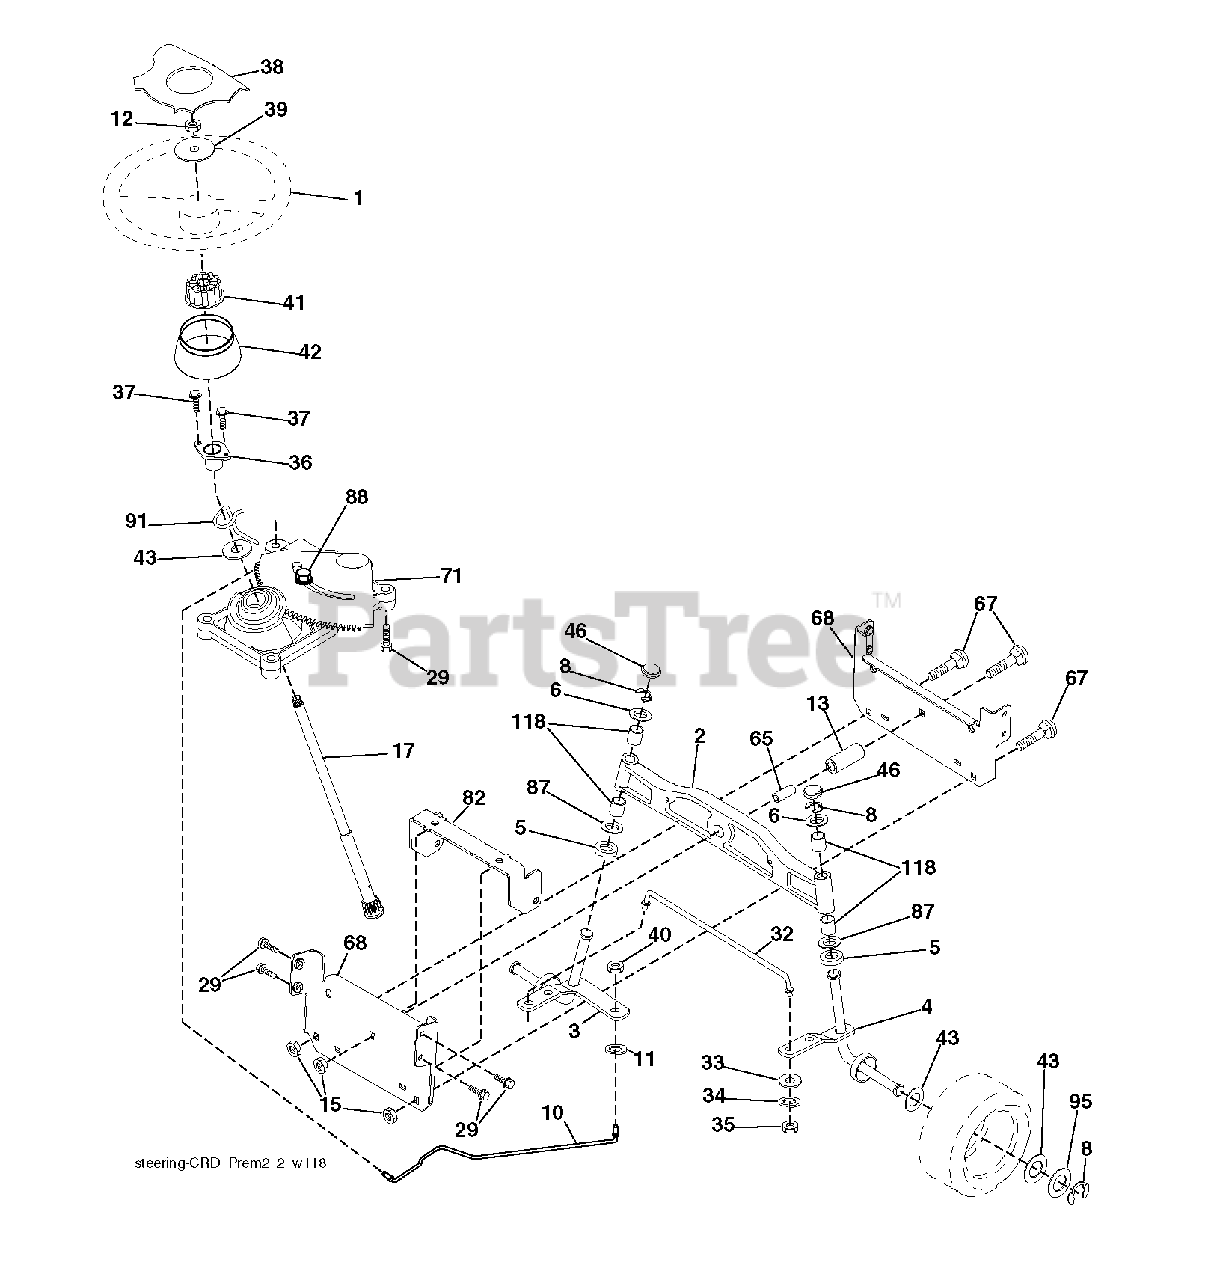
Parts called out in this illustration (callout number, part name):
1	WHEEL.STEERING.PREM.2.BLK
2	AXLE.ASM.LT.CAST.LGHTWGHT
3	SPINDLE.ASM.LH.15"TIRES
4	SPINDLE.ASM.RH.15"TIRES
8	RING CLIP
10	DRAGLINK.15".TIRES.2001
11	WASHER, LOCK 3/8
12	NUT.HEX.1/2-20
13	TUBE, PIVOT AXLE
15	NUT
17	SHAFT ASM STRG
29	SCREW, 3/8-16X3/4
33	WASHER M
34	LOCKWASHER
35	NUT, CROWNLOCK
36	BUSHING, STRG. BLK
38	INSERT.CAP.STRG.WH.BLACK
39	WASHER 9/16"ID, 2 3/8"OD
40	NUT CROWNLOCK 3/8-24
41	ADAPTER, WHEEL STNG..
46	CAP.SPINDLE
65	SPACER.BRACE.AXLE
67	BOLT CARRIAGE
68	BRACE.AXLE.15"TIRES
71	STEERING ASM
82	BRACKET.SUSP.CHASSIS.FRONT.15
87	WASHER, FLAT .781 X 1 1/2"
88	BOLT, SHOULDER 7/16-20
91	CLIP.STEERING
95	WASHER.HARDENED
118	BUSHING, AXLE CAST
